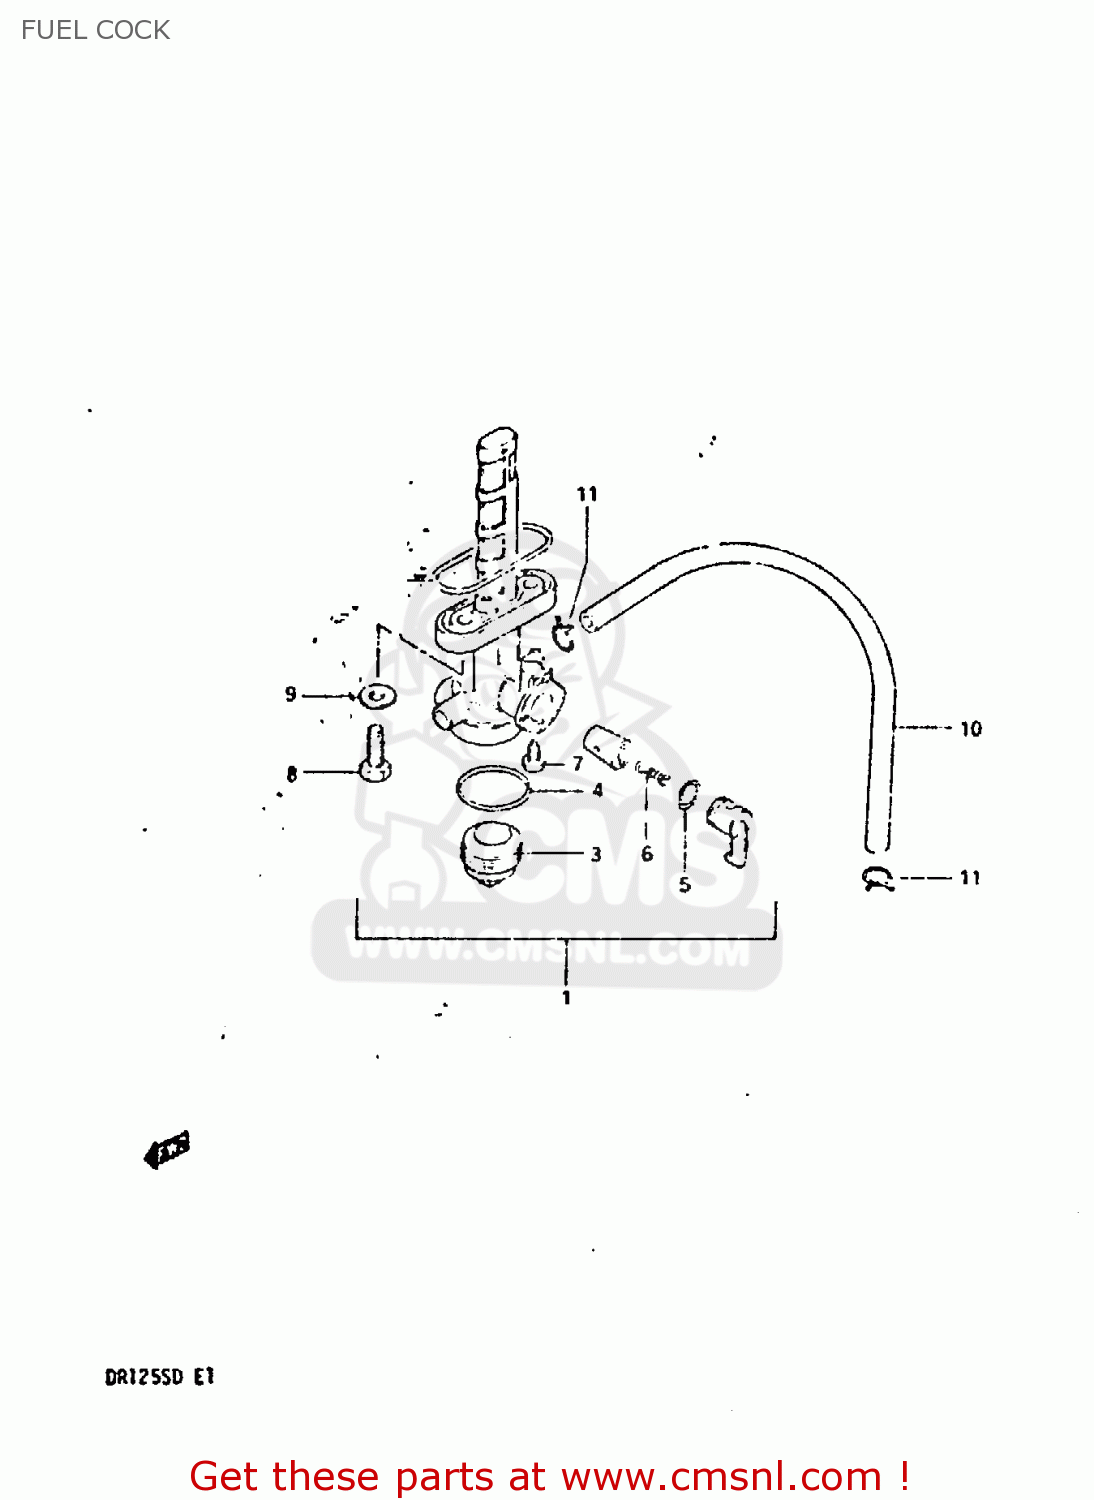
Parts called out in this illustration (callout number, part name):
1	COCK ASSEMBLY,FUEL
2	O RING,FUEL COCK
3	CUP,STRAINER
4	GASKET,FILTER (NAS)
5	O-RING
6	SPRING
7	SCREW
8	BOLT(6X20)
9	GASKET
10	HOSE
11	CLIP
